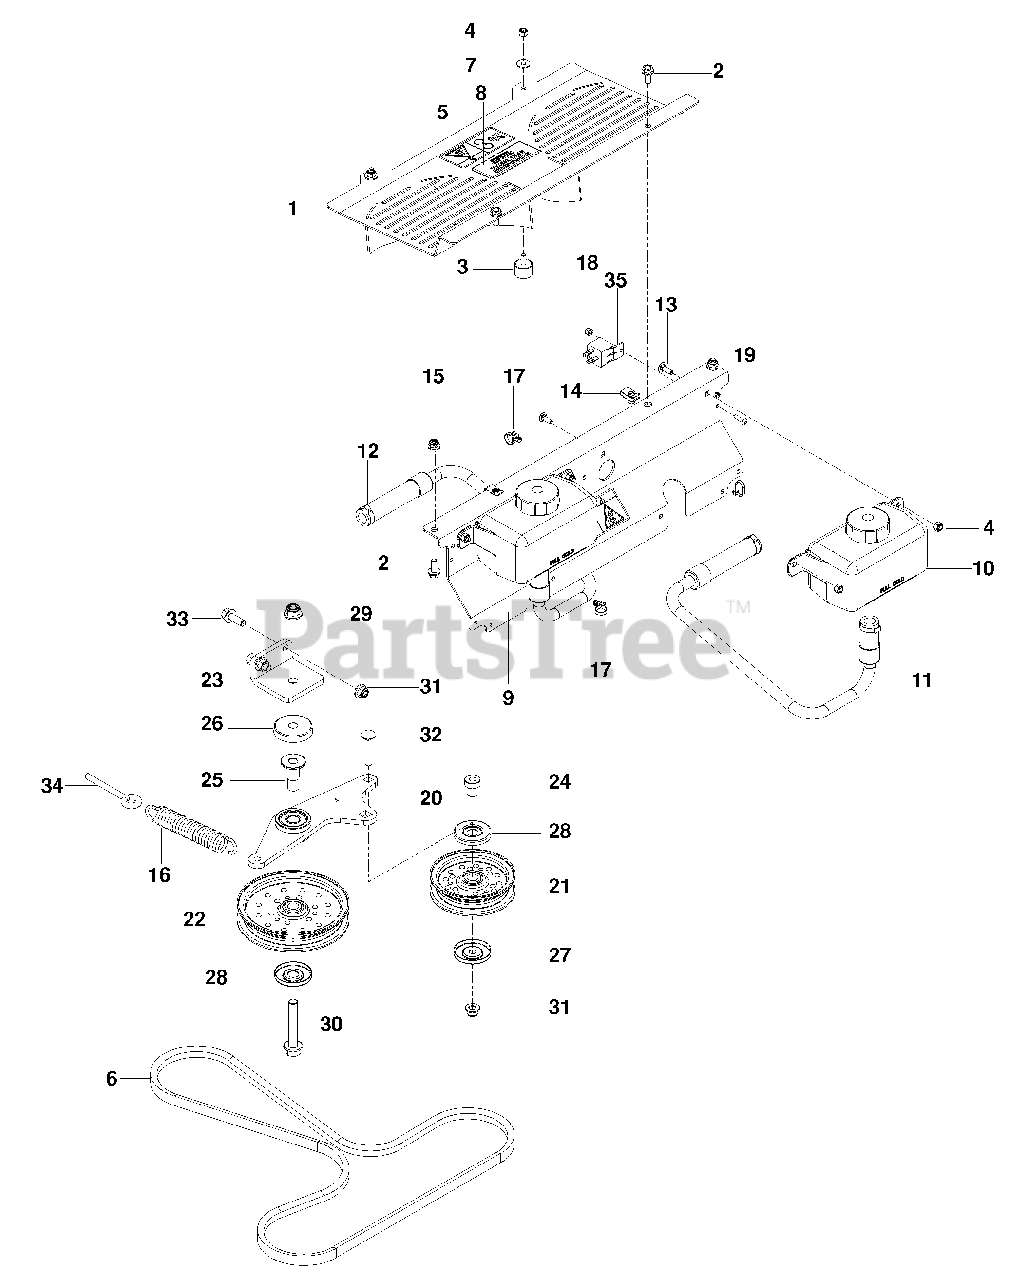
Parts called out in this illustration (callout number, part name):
1	Shield, Fan
2	Bolt 7/16-20 X 1 1/2 Hex Nyl
3	Bumper, Male Stud 1/4-20
4	Nut 1/4-20 Nyloc
5	Decal, Belt Drives
7	Washer 1/4 Flat
8	Decal, Hydrogear
9	Mount, Expansion Tank
10	Tank, Expansion
13	Bolt 1/4-20 X 3/4 Gr2 Rd Hd
14	Retainer, U Type
15	Nut 5/16-18 Hex Flg Nyloc
16	Spring, Extension
17	Tie Wrap W/Clip
18	Nut #10-24 Hex Nyloc
19	Screw #10-24 X 3/4 Skt Hd
20	Arm, Idler W/ Bearings
21	Pulley, Idler
22	Idler, Flat 5 1/2
23	Mount, Idler
24	Pivot, Idler
25	Bushing, Pivot
26	Shield, Dust, 1/2" Id
27	Shield, Dust
28	Shield, Dust
29	Nut 1/2-13 Flg Nyloc
30	Bolt 1/2-13 X 3 Hex Flg
31	Nut 3/8-16 Flg Nyloc
32	Bolt 3/8-16 X 2 Rd Hd
33	Screw 3/8-16 X 1 Hex Flg
34	Eye Bolt 5/16 X 3 1/2
